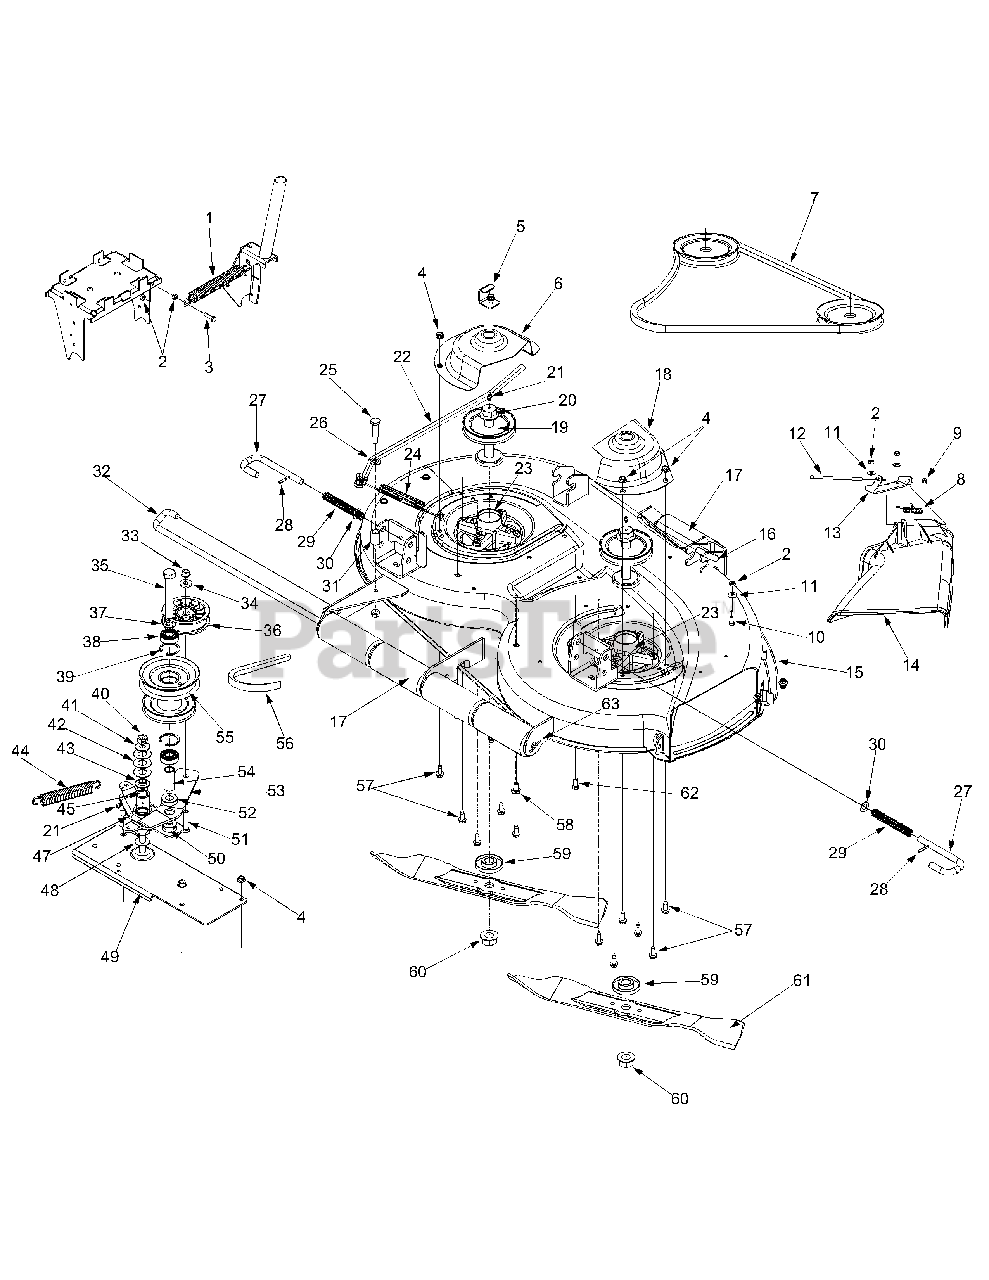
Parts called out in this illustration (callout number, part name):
1	Extension Spring .94 OD x 7.57 Lg
2	Hex Nut 1/4-20
3	Hex Cap Screw 1/4-20 x 1.0
4	Flange Lock Nut 5/16-18
7	V-Belt
8	Torsion Spring
9	Speed Cap Nut
10	Hex Cap Screw 1/4-20 x .620
11	Bell Washer .265 OD x .75 ID
12	Hinge Pin .25 Dia. x 6.75 Lg
13	Hinge Mounting Bracket
14	Deflector Ass’y Chute
19	Pulley 4.0 Dia
20	Spindle Bolt 3/4-16 x 4.25
21	Grease Fitting 3/16
22	Engag Rod Ass’y
23	Deck Spindle Ass’y
24	Extension Spring .75 OD x 8.63 Lg
25	Shoulder Screw .498 x 1.45 Lg
26	Flat Washer .531 OD x .93 OD
27	Support Mower Pin
29	Compression Spring .63 OD x 6.3 Lg
30	Flat Washer .536 ID x .930 OD
31	Spacer .550 ID x .750 OD
32	Deck Roller Pin
33	Flange Lock Nut 3/8-16
34	Flat Washer .385 OD x 1.0 OD
35	Hex Cap Screw 5/8-18 x 4.25
36	Flat Idler Pulley 3.5 OD
37	Flat Washer 5/8 ID x 1.0 OD
38	Bearing .625 ID x 1.574 OD
39	Snap Ring
40	Lock Nut 1/2-20
41	Flat Washer 1/2 ID x 1.25 OD
42	Flat Washer .76 ID x 1.49 OD
43	Flange Bearing 3/4 ID x .52 Lg
44	Extension Spring 1.0 OD x 6.140 Lg
45	Spacer .50 OD x .75 ID
51	Hex Cap Screw 3/8-16 x 1.75
52	Shoulder Spacer .875 Dia x .245
56	V-Belt
57	Hex Washer Screw 5/16-18 x .75
58	Carriage Bolt 3/8-16 x .75
59	Deck Spindle Spacer
60	Hex Flange Nut 3/4-16
61	Blade
62	Hex Cap Screw 5/16-18 x .75
